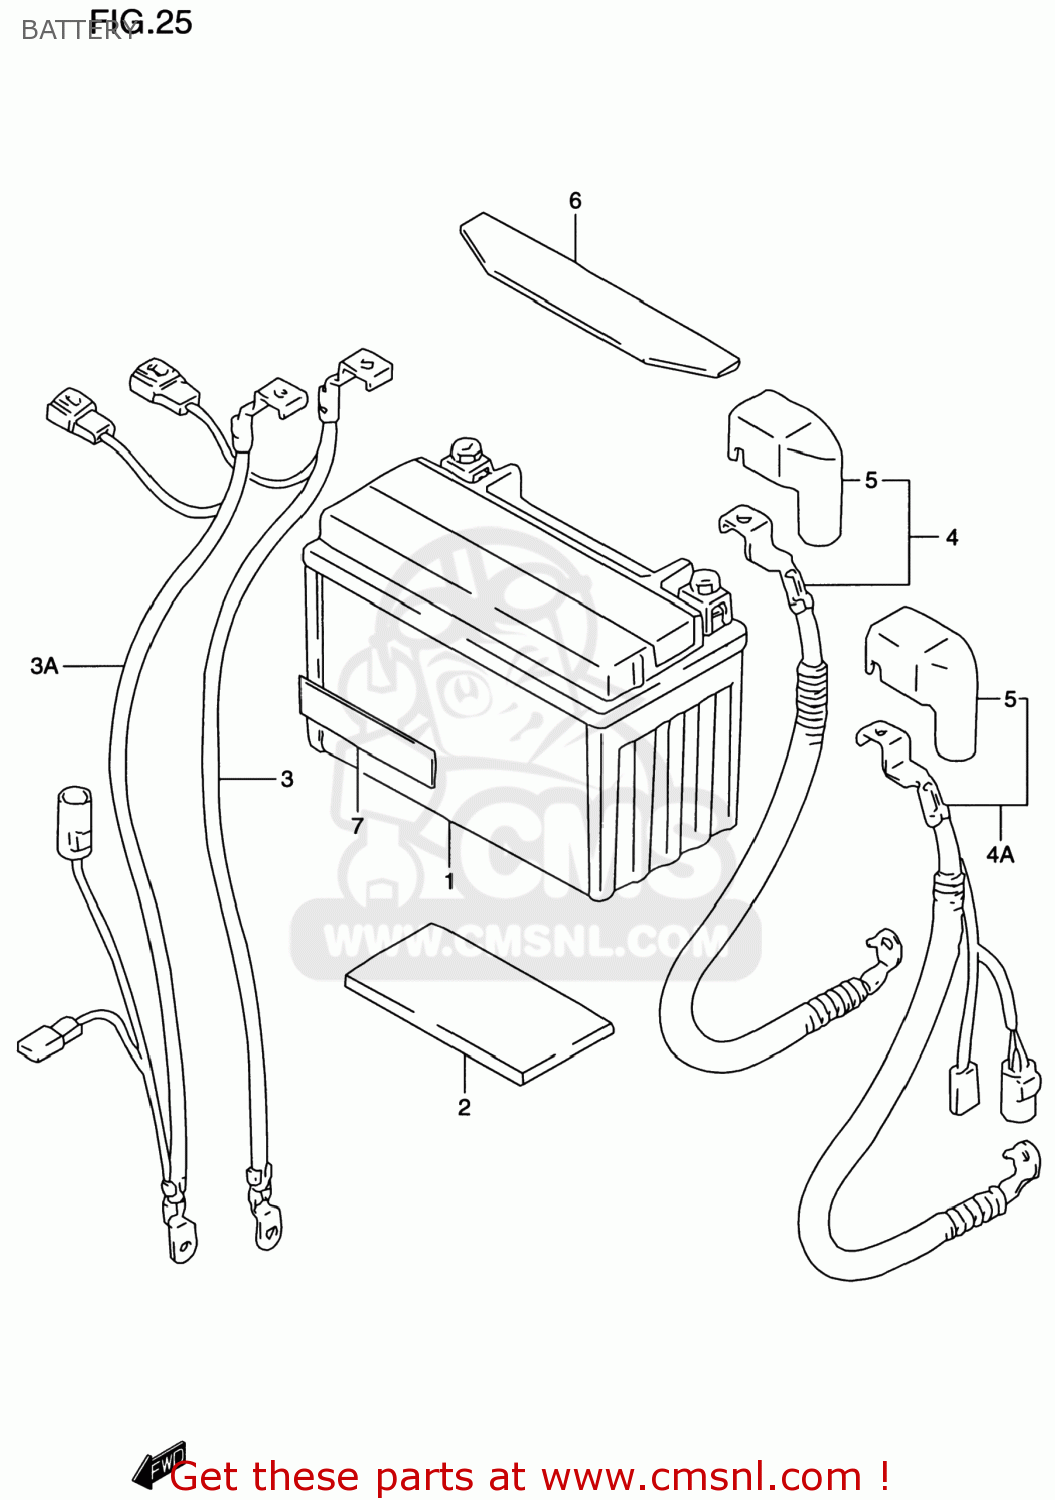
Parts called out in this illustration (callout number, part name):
1	BATTERY ASSEMBLY (12V) YTX
2	PROTECTOR(170X95X3.0)
3	WIRE,BATTERY MINUS
3A	WIRE,BATTERY MINUS
4	WIRE,BATTERY PLUS LEAD
4A	WIRE,BATTERY PLUS
5	CAP,BATTERY PLUS TERMINAL
6	PROTECTOR,BATTERY
7	PROTECTOR(20X90)X1.0
